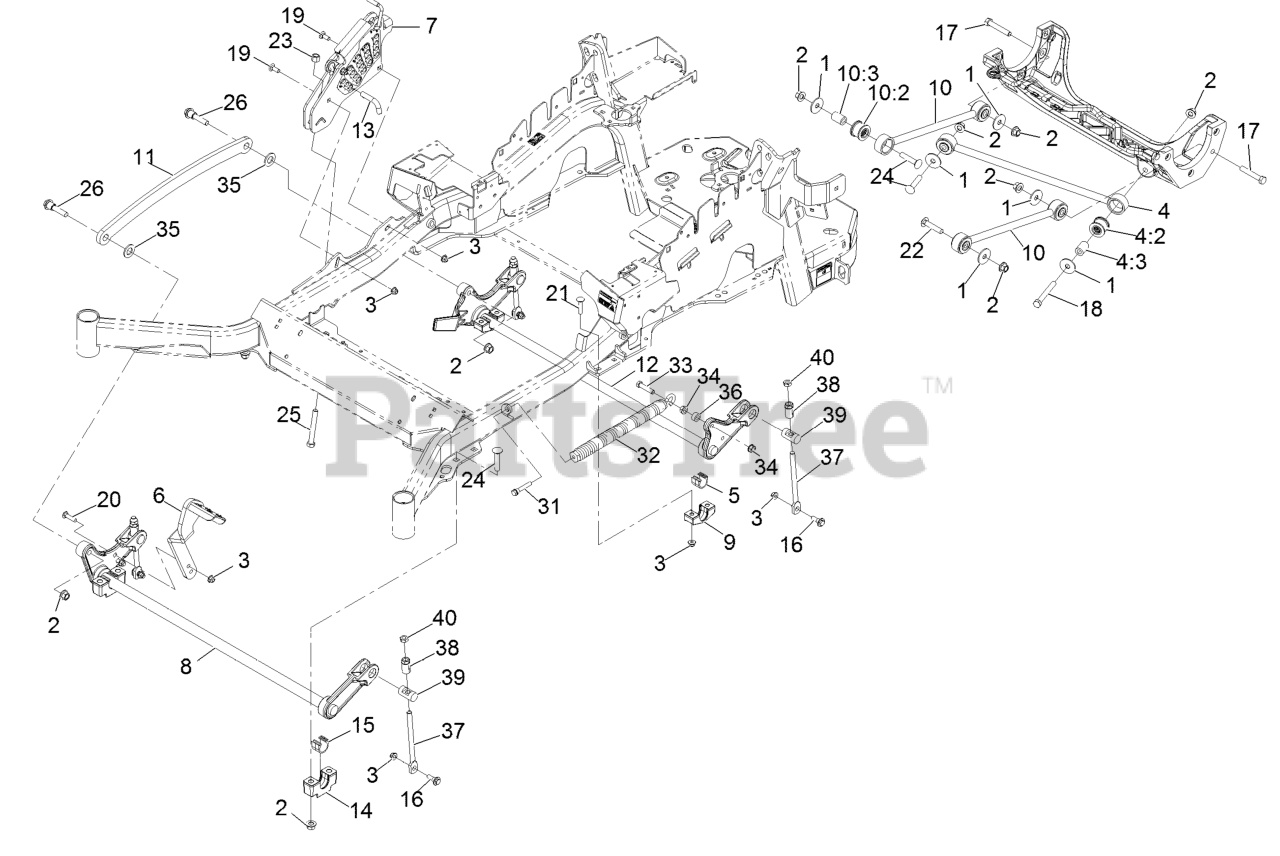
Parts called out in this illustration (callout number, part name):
1	WASHER-THRUST
2	Nut-Lock 1/2-13
3	NUT-HF, NI
4	PANHARD ROD ASM
4:2	BUSHING-SUSPENSION, RUBBER
5	BEARING-CROSS SHAFT, REAR
6	LEVER-FOOT
7	HOC ASM
10	DECK STRUT ASM
10:2	BUSHING-SUSPENSION, RUBBER
11	LINK-LIFT, DECK
12	LIFT-DECK, REAR
13	PIN-HOC
14	SUPPORT-CROSS SHAFT, BEARING
15	BEARING-CROSS SHAFT, FRON
16	SCREW-SHOULDER, HHF
17	SCREW-HH
18	SCREW-HH
19	BOLT-CARR
20	SCREW-CARR
21	SCREW-CARR
22	SCREW-CARR
23	NUT-LOCK, NI
24	Bolt-Carriage 1/2-13 X 2 1/2 Spl Neck
25	BOLT-TAP
26	SCREW-HHF, SHOULDER
31	BOLT-SHOULDER
32	SPRING-EXTENSION
33	SCREW-HH
35	WASHER-FLAT
37	LINK-ADJUSTER, DECK LIFT
38	ADJUSTER-LIFT, DECK
39	TRUNNION
40	NUT-JAM
